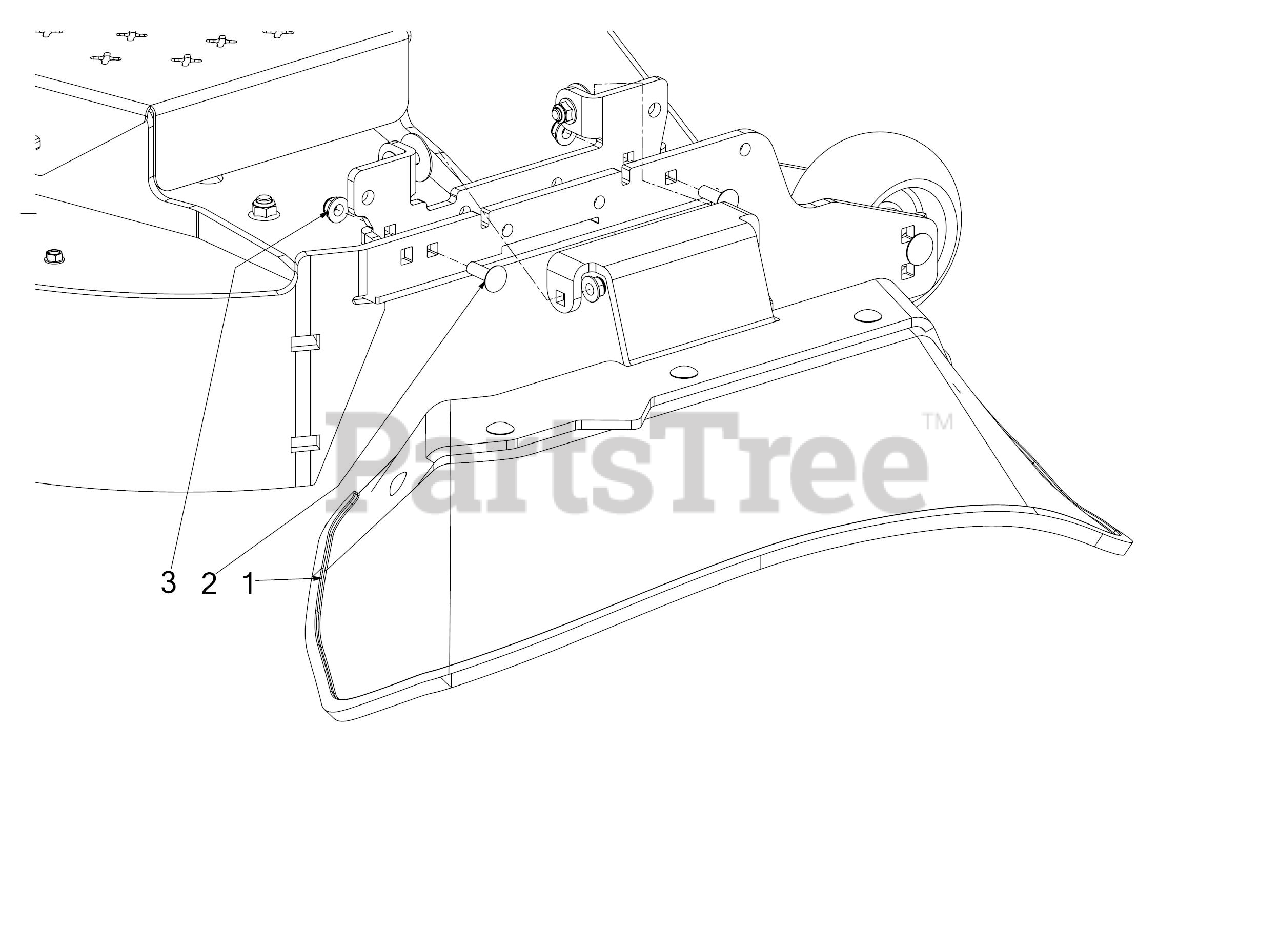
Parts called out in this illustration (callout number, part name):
1	DECK CHUTE ASSEMBLY
2	CARRIAGE BOLT 5/16-18 x 1.00
3	FLANGE LOCK NUT 5/16-18
